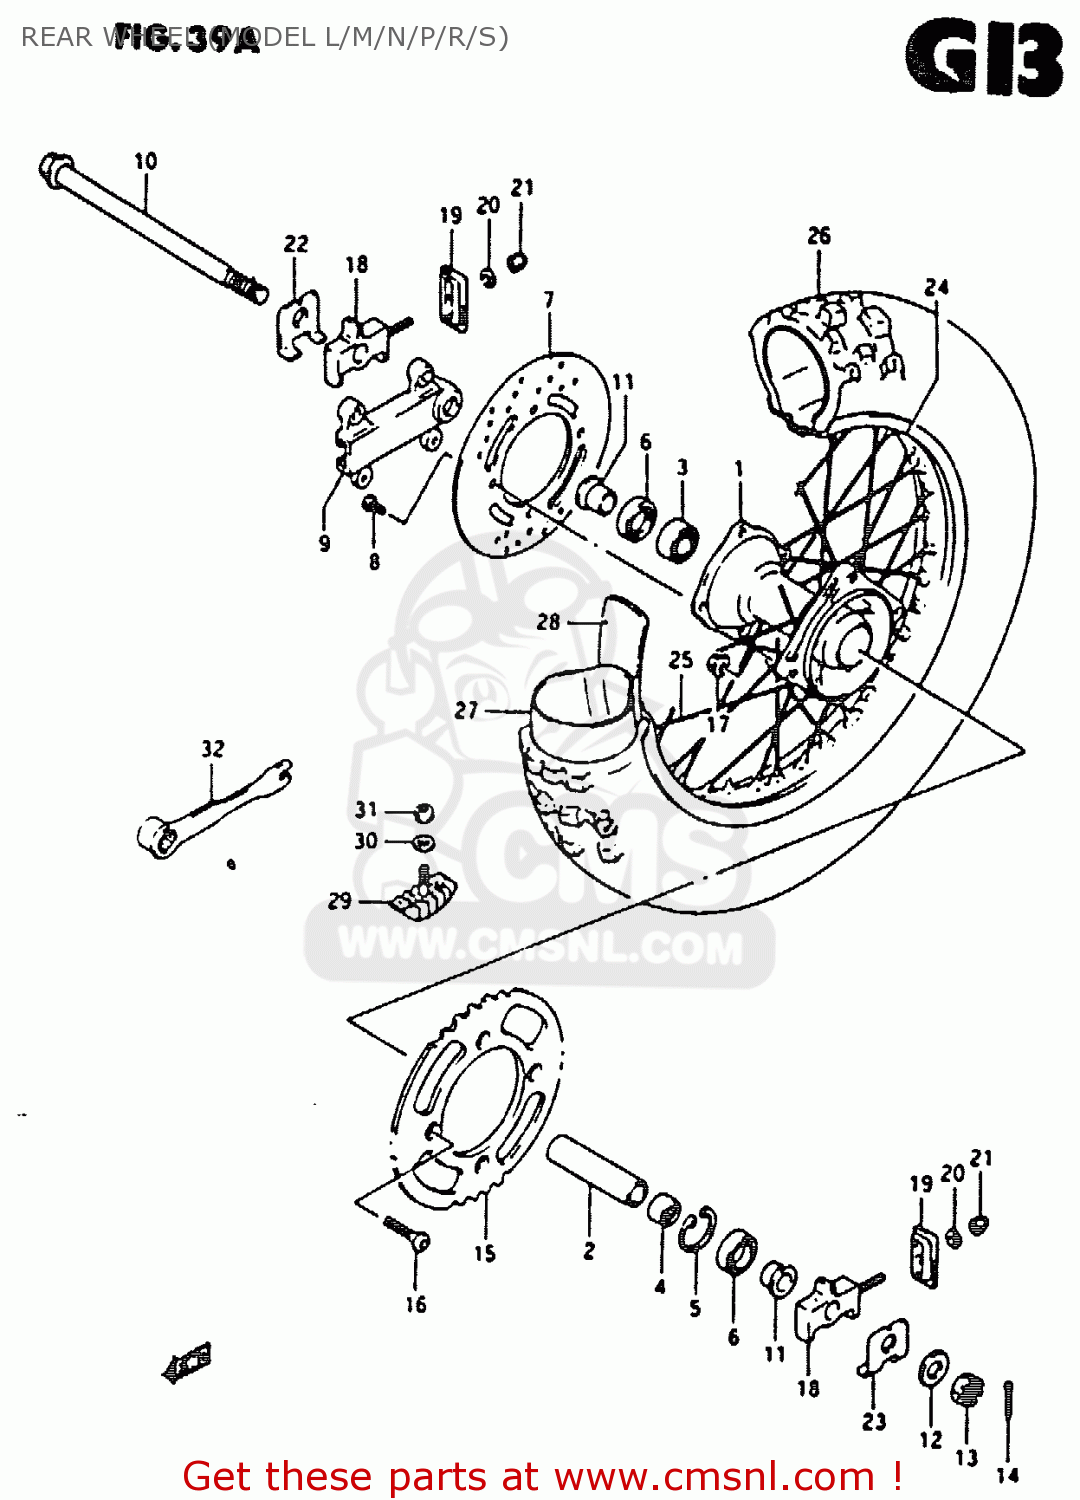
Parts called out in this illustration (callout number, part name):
1	HUB,REAR WHEEL
2	SPACER,RR HUB BEARING
3	BEARING
4	BEARING(15X35X11)
5	CIRCLIP
6	SEAL,OIL(20X35X7)
7	DISC,REAR BRAKE
8	SCREW
9	BRACKET,REAR CALIPER
10	AXLE,RR
11	SPACER,REAR AXLE
12	WASHER
13	NUT
14	COTTER PIN
15	SPROCKET,RR(49T)
16	BOLT(8X30.5)
17	NUT
18	ADJUSTER,CHAIN
19	PLATE,CHAIN ADJUSTER
20	WASHER
21	NUT 6MM
22	WASHER,CHAIN ADJUSTER RH
23	WASHER,CHAIN ADJUSTER,L
24	RIM,RR WHEEL(1.60X14 AL)
25	SPOKE SET,RR WHEEL
26	TIRE,RR(90/100 14)
27	TUBE ASSY,WHEEL INNER
28	PROTECTOR,WHL INR TUBE
29	STOPPER,BEAD
30	WASHER
31	NUT
32	PROTECTOR,INNER TUBE
33	RIM,REAR WHEEL (1.60X14)
34	SPOKE SET
35	STOPPER,BEAD
36	NUT
37	WASHER
38	SPARK PLUG WRENCH 21 & SPANNER 5.1
